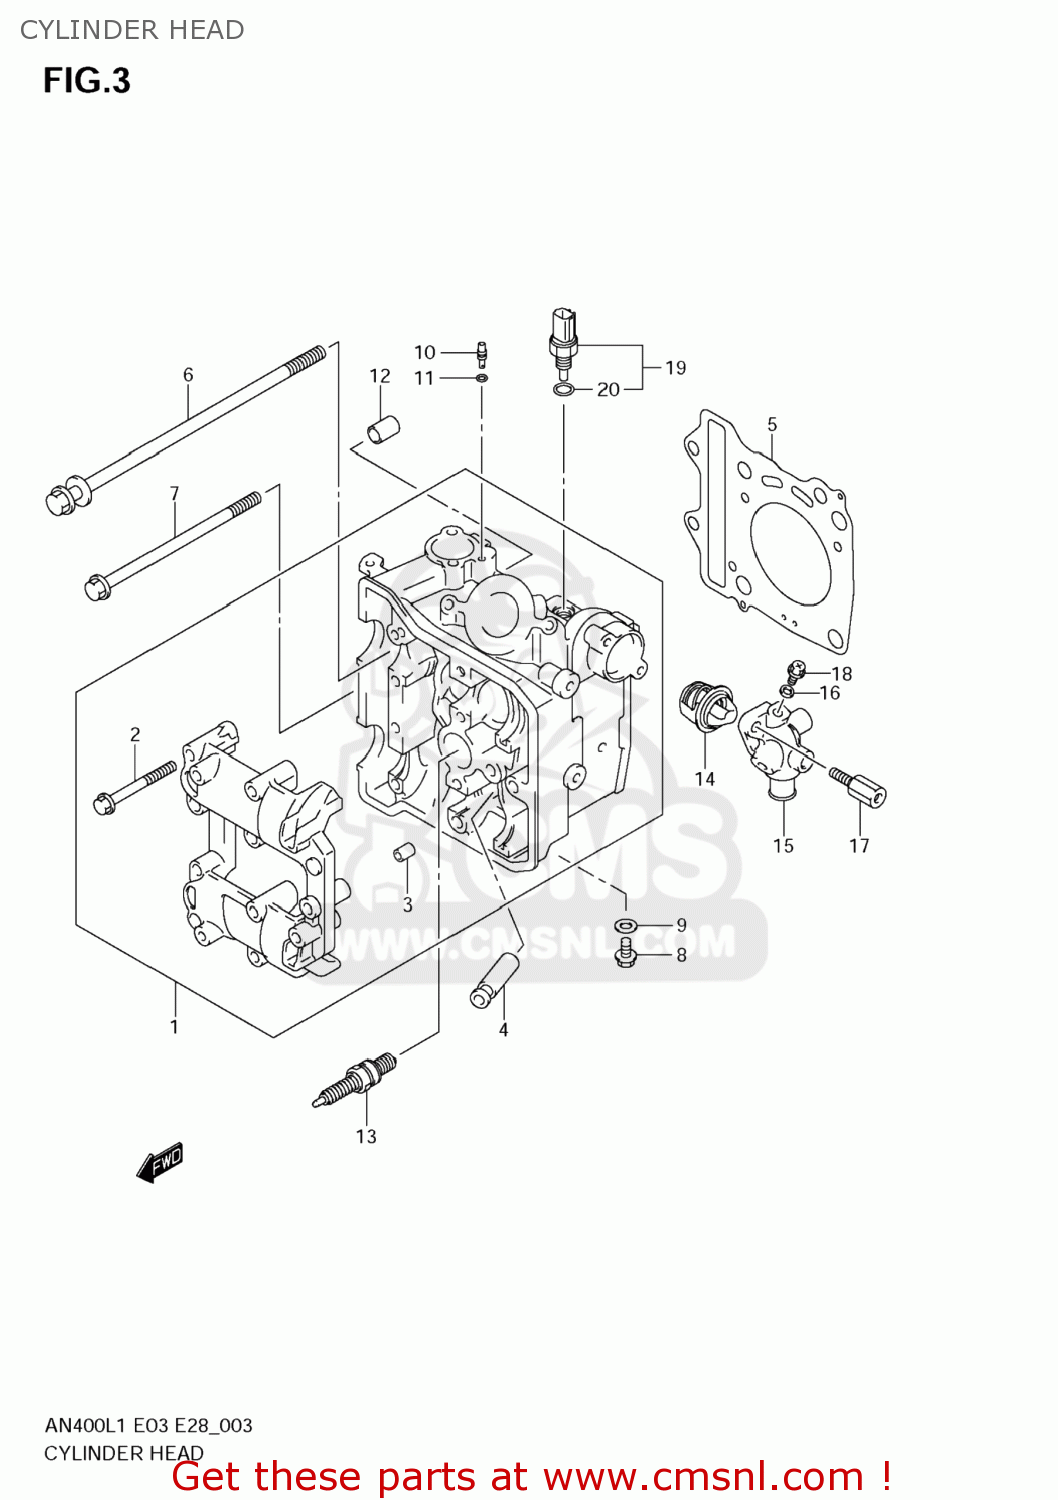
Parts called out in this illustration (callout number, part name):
1	HEAD ASSY,CYLINDER
2	BOLT(6X45)
3	PIN(6.2X8X11)
4	GUIDE,VALVE
5	GASKET,CYLINDER HEAD (NAS)
6	BOLT(8X130)
7	BOLT,CYLINDER HEAD(L:190)
8	BOLT(6X12)
9	GASKET(5.8X13X1.2) (NAS)
10	JET(8)
11	O RING(D:1.2,ID:4)
12	PIN
13	PLUG,SPARK(CR7E)
14	THERMOSTAT,WATER
15	COVER,THERMOSTAT
16	GASKET(6.4X11.5X0.8) (NAS)
17	BOLT,THERMOSTAT COVER
18	UNION BOLT,AIR VENT
19	SENSOR,WATER TEMP
20	O RING
